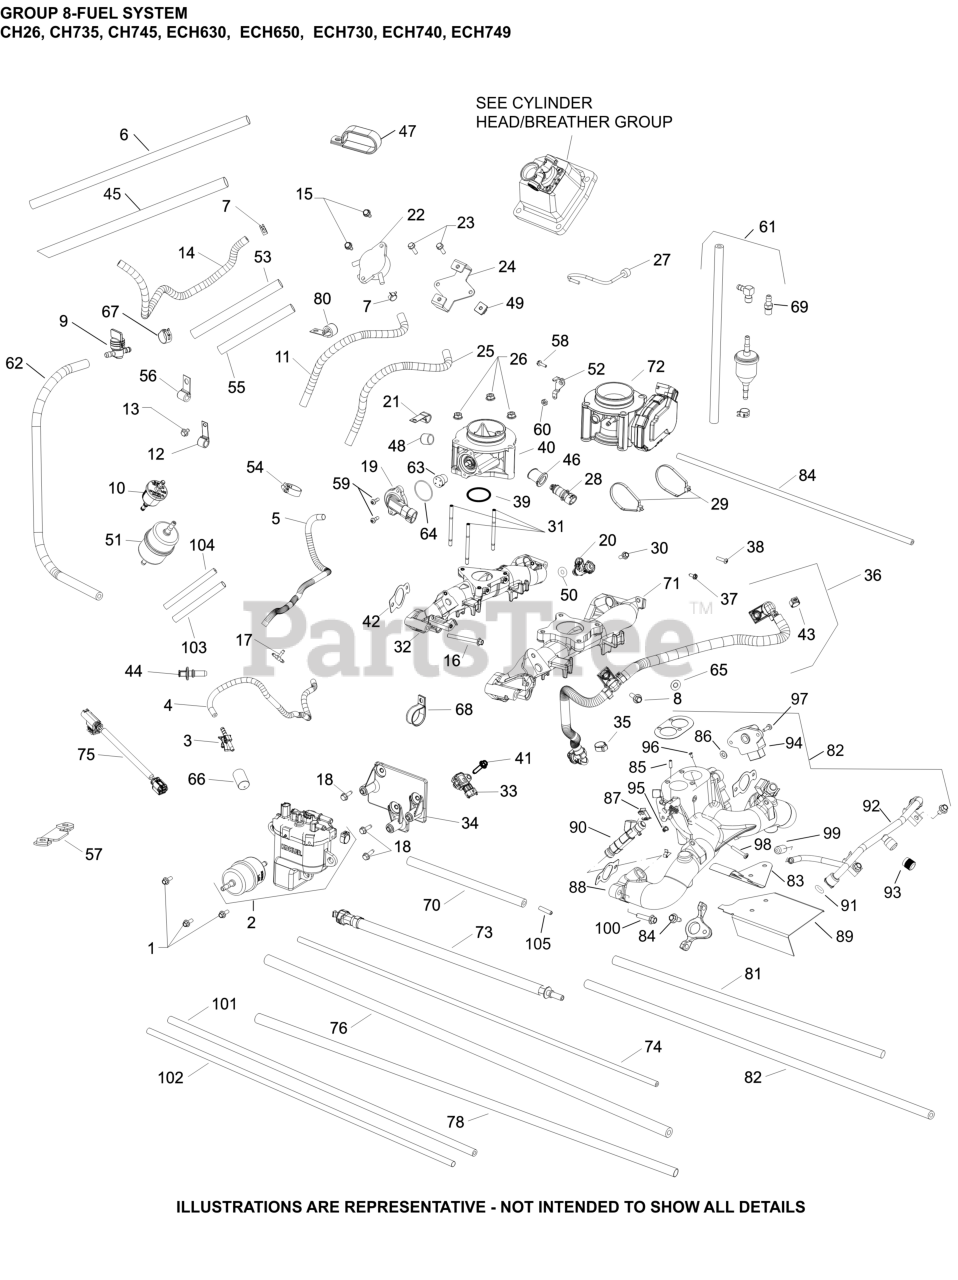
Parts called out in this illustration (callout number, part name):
2	KIT, FUEL PUMP MODULE
4	HOSE, EVAPORATIVE (15.0)
5	SLEEVE, ANTI-ABRASION
8	SCREW, FLG M6x1.0x20
15	SCREW, THREAD FORMING
16	SCREW, FLG M6X1.0X60
17	TEE CONNECTOR
20	INJECTOR, FUEL
21	CLIP, CABLE
25	SLEEVE, ANTI ABRASION-USE 25 431 12-S
33	SENSOR, T-MAP
35	CLAMP, HOSE
36	FUEL HOSE ASSEMBLY,ECH680-ECH749
42	KIT, INTAKE MANIFOLD GASKET
43	CLAMP, OETIKER
50	KIT, FUEL INJECTOR O-RING
51	FILTER, FUEL
55	SLEEVE, ANTI ABRASION -USE 25 431 12-S
65	CLIP, RETAINER
67	CLAMP, SPRING HOSE
68	CLAMP, INSULATED
70	HOSE, FUEL LOW-PERMEATION
71	MANIFOLD, INTAKE - ETB HORIZONTAL
72	BODY, ELECTRONIC THROTTLE ASM 30 DIA
80	CLIP, CABLE (KM)
104	HOSE, EVAPORATIVE (4.5)
105	CAP, MASKING
